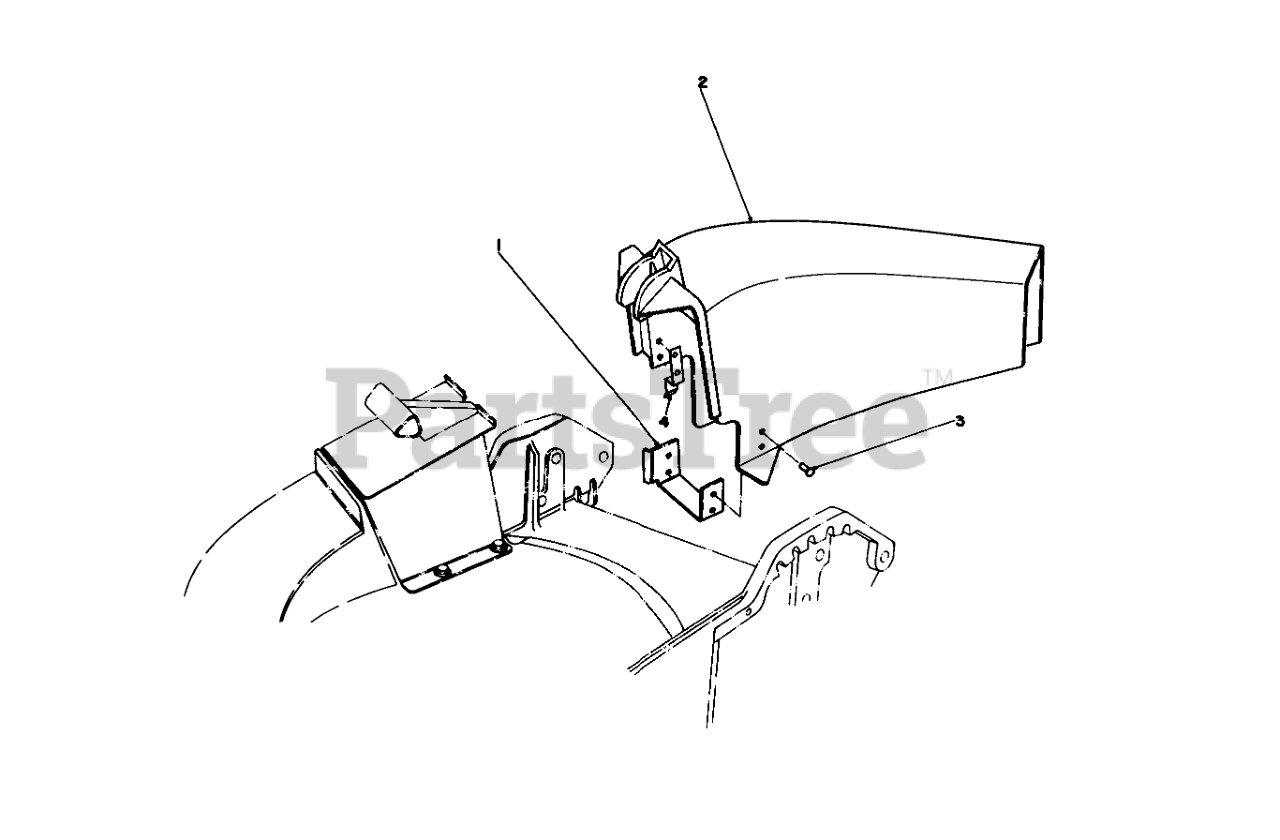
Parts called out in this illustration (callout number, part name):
1	CHUTE BRACKET
2	Chute Discharae
3	RIVET
4	CHUTE TAB
